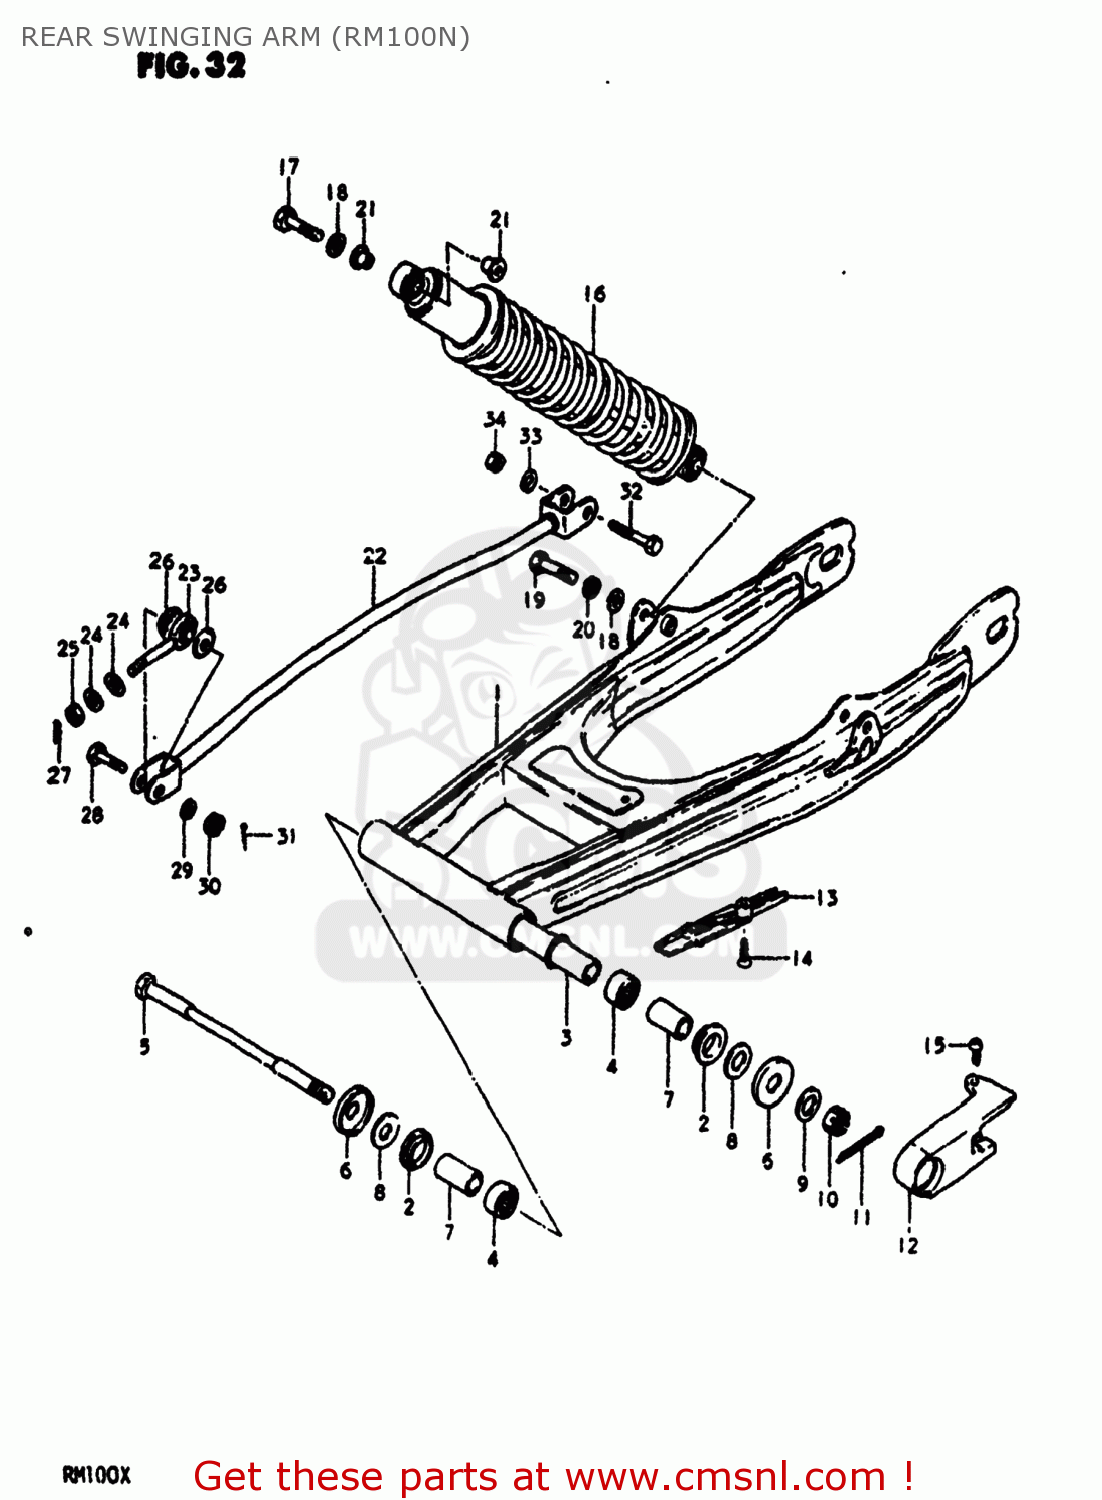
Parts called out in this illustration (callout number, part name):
1	SWING ARM ASSEMBLY,REAR
2	BUSH,RR SWINGINGARM PIVOT
3	SPACER,SWING ARM,CENTER
4	ROLLER BEARING (17X24X2
5	SHAFT,RR SWINGINGARM PIVOT
6	COVER,REAR SWING ARM DUST
7	SPACER,RR SWGARM PIVOT
8	WASHER
9	WASHER
10	NUT, REAR AXLE
11	COTTER PIN
12	BUFFER,CHAIN TOUCH DEFLECTOR
13	BUFFER,CHAIN TOUCH DEFLECTOR
14	SCREW
15	SCREW
16	ABSORBER ASSEMBLY,REAR SHOCK
17	BOLT
18	WASHER
19	BOLT 10X40
20	LOCK WASHER
21	SPACER,RR SHK ABS INNER
22	TORQUE LINK,REAR
23	BEARING
24	WASHER
25	NUT
26	DUST SEAL,TORQUE LINK FR BRG
27	PIN
28	BOLT 8X28
29	WASHER
30	NUT 8MM
31	PIN 20X20
32	BOLT 10X40
33	WASHER
34	NUT
